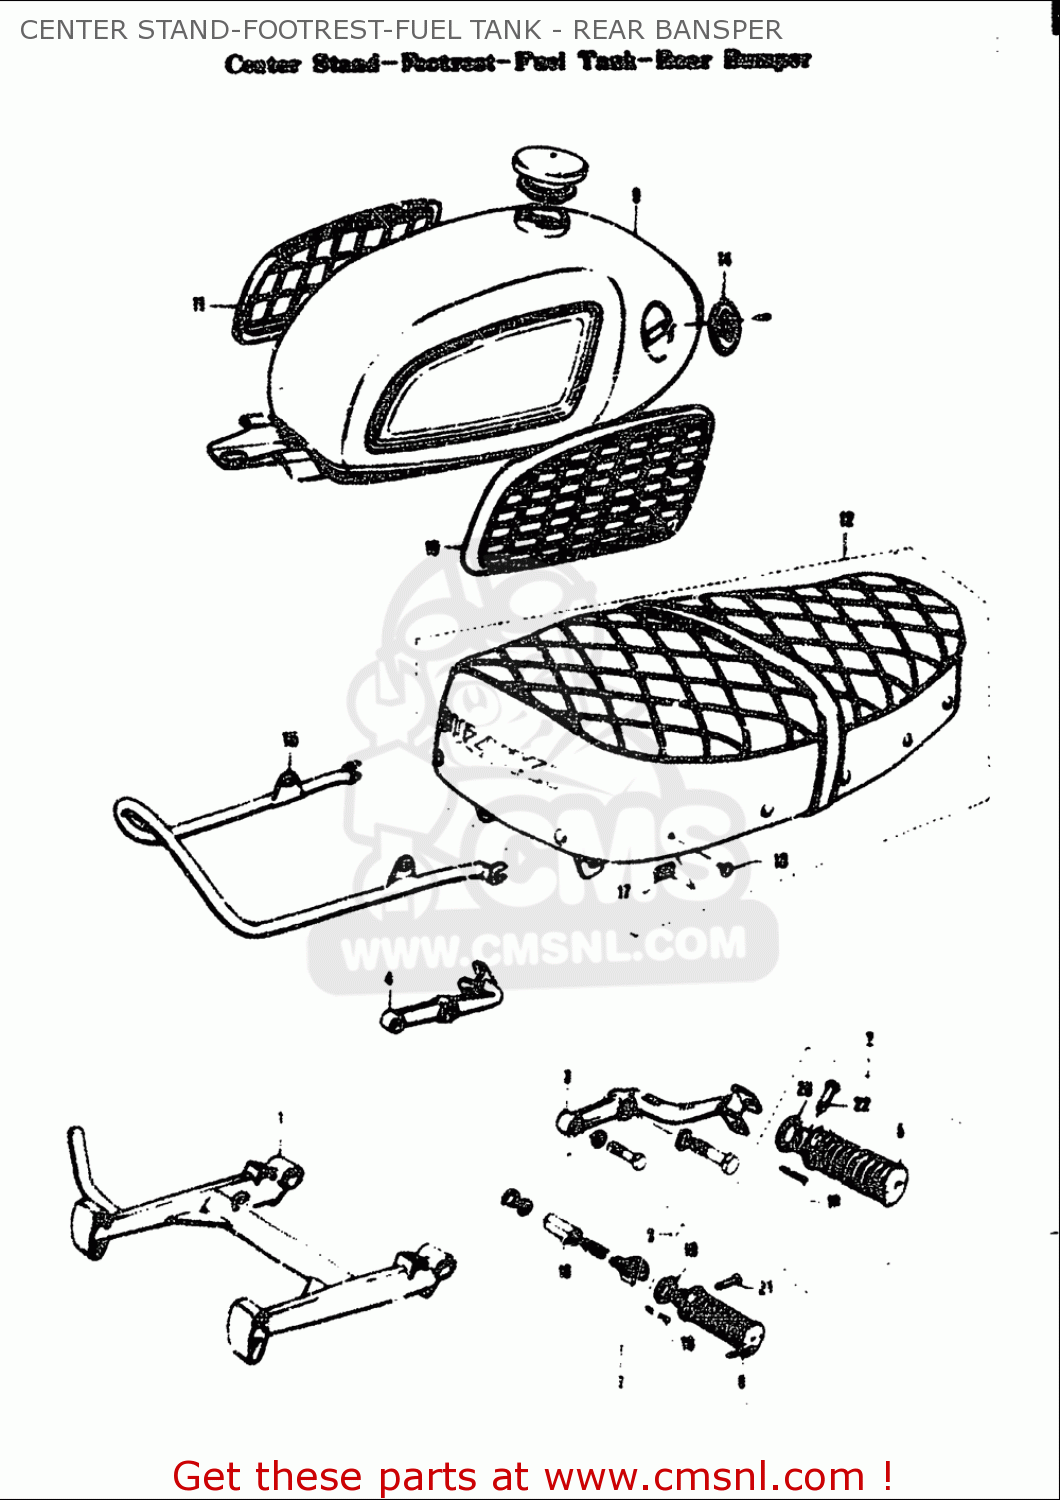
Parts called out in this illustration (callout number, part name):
18	NUT
19	WASHER(19.5X32X2)
20	WASHER(22.5X38X1)
21	PIN
22	PIN
